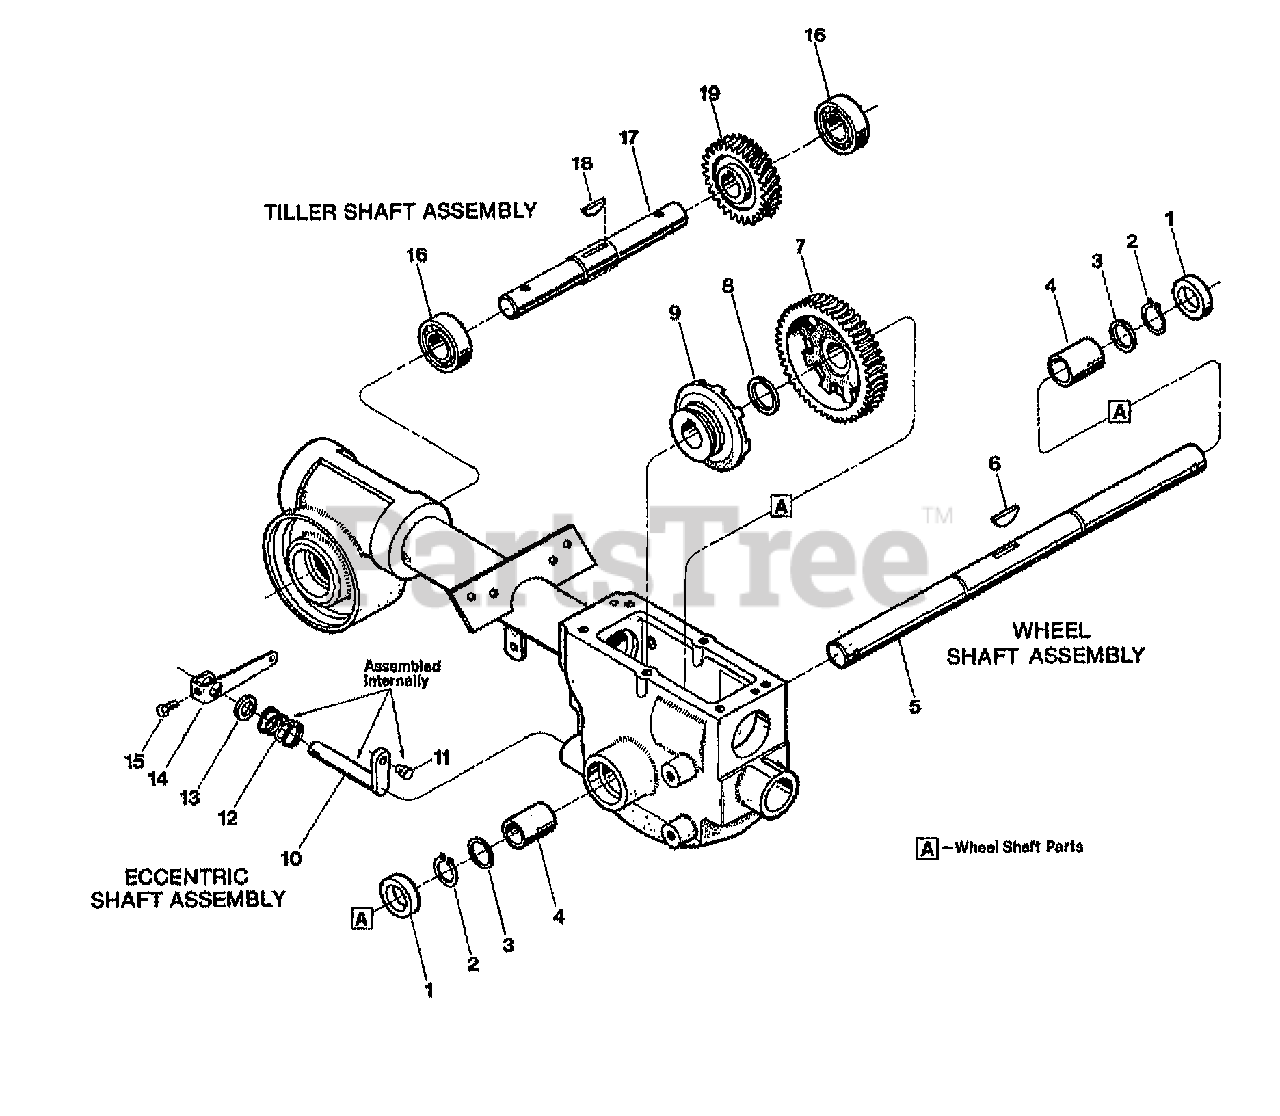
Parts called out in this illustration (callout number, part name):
1	SEAL-OIL WHEELSHAFT
2	RING-HEAVY EXT .906 ID
3	SHIM-1.375X1.015X.062
4	BUSHING-1.25X1.005X1.5
5	WHEELSHAFT W/KEY (AXLE) - (INCL. 6)
6	KEY-HI PRO .25X1.312
7	GEAR-WHEEL DRIVE MACH
8	WASHER-1.468X1.016X.062
9	CLUTCH-MACH
10	WELD-ECCENTRIC
11	PIN-.375 X .72
12	SPRING-.850 X .875 LONG
13	SEAL-OIL ECCENTRIC
14	LEVER-CABLE ADJ PNT
15	SCR-HH 1/4-20X.5 GR5 YEL
16	BEARING-BALL
17	SHAFT-W/KEY (TILLER)
18	KEY-WOODRUFF .25X1.12
19	WORM GEAR - BRONZE, TILLER DRIVE
19	WORM GEAR - BRONZE
